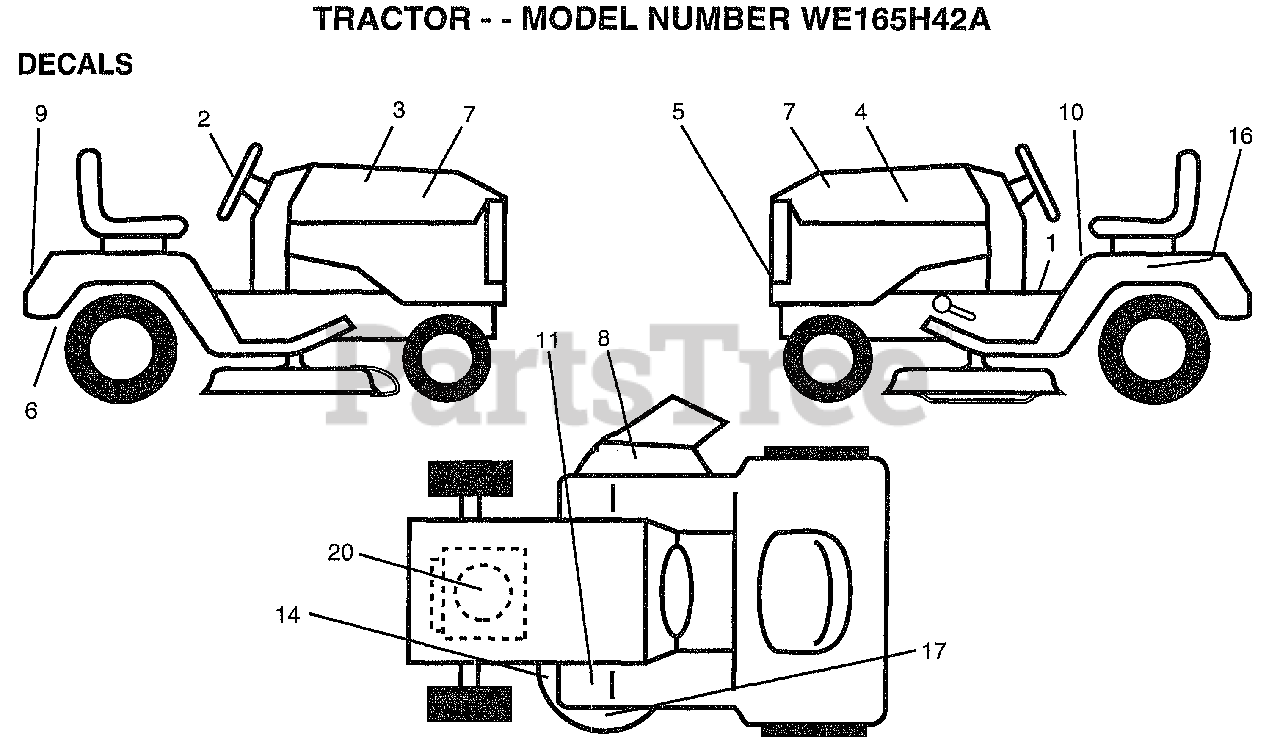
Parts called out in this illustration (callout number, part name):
1	DECAL SADDLE OPER
2	DECAL, INS STRG WH
3	DECAL.HOOD.RH.
4	DECAL.HOOD.LH
5	DECAL, GRILLE LENS
6	DECAL DRAWBAR LH
7	DECAL.PANEL.SIDE
8	"DECAL, WARNING"
9	DECAL.FENDER.LOGO
10	DECAL.CAUT.ENG/FR
11	DECAL T
14	"DECAL-SCHEM,BELT"
16	DECAL.BATRY.3-3908
17	DECAL, DECK GRASSEATER
20	DECAL ENGINE
